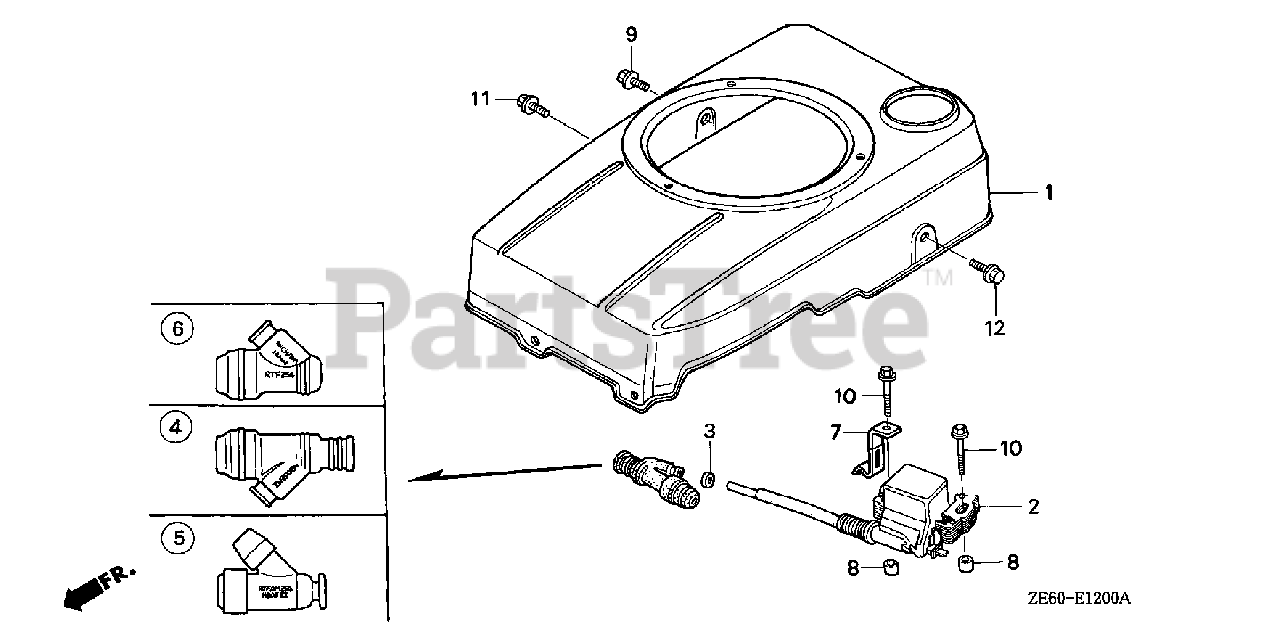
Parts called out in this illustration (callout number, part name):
1	COVER, FAN *R8* (BRIGHT RED)
2	COIL ASSY., IGNITION
3	GROMMET, IGNITION WIRE
5	CAP ASSY., NOISE SUPPRESSOR
9	BOLT, FLANGE (6X12) (CT200)
10	BOLT, FLANGE (6X25) (CT200)
11	BOLT, FLANGE (6X10)
12	BOLT, FLANGE (6X12) (CT200)
